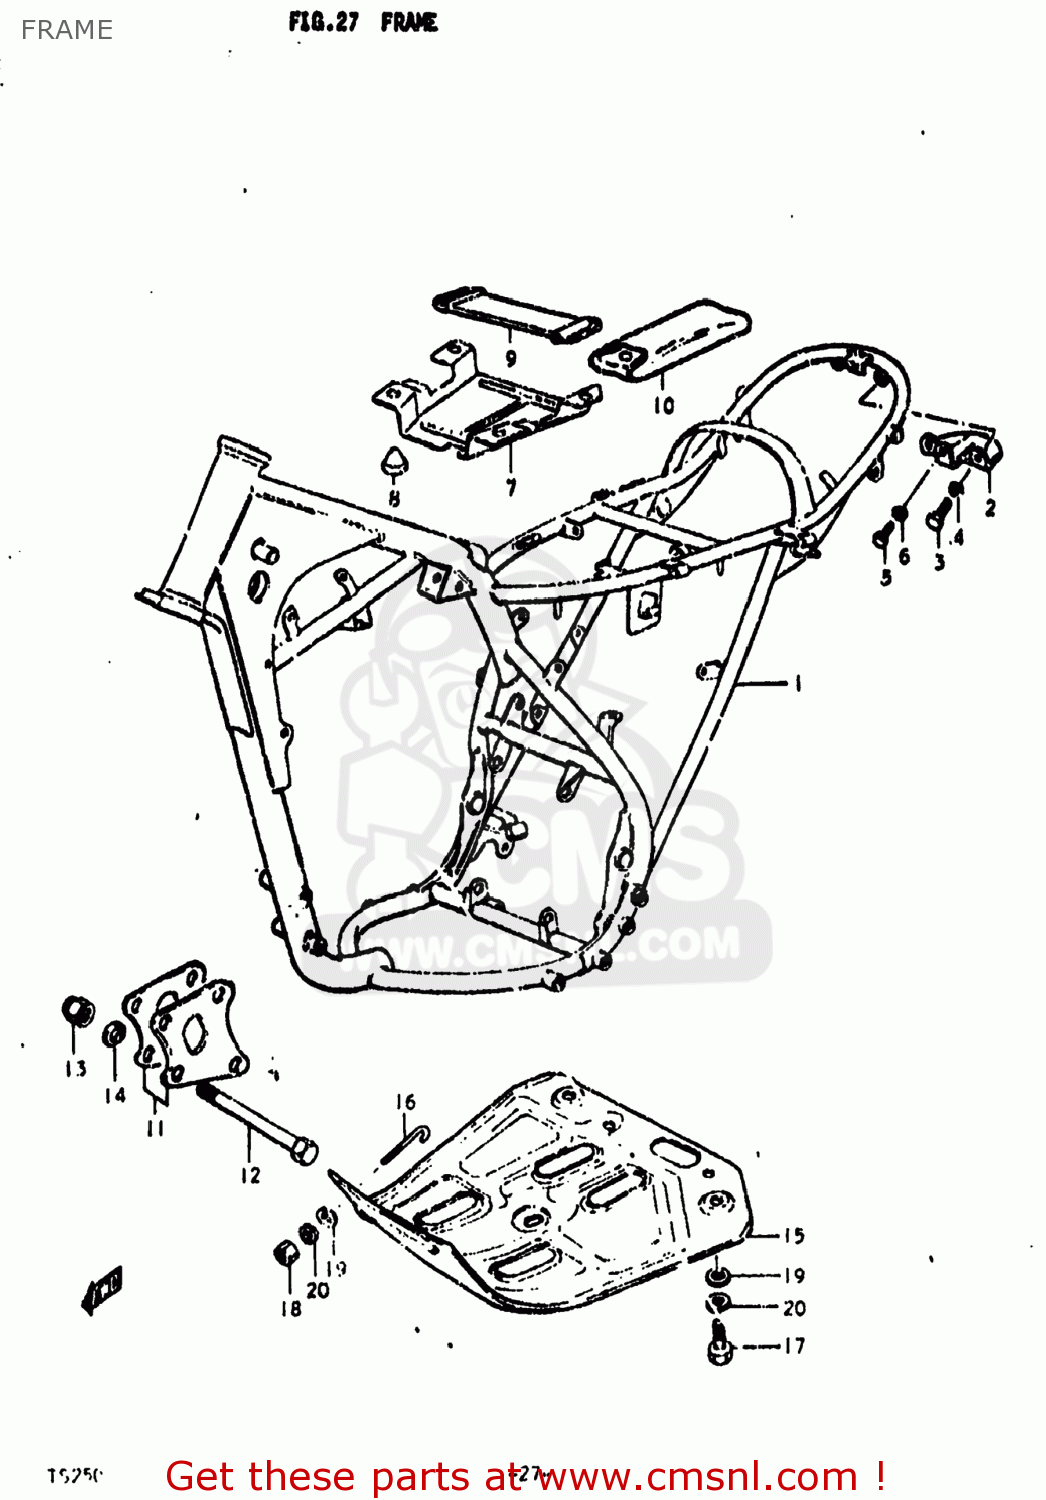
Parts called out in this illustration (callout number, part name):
1	FRAME
3	BOLT
4	LOCK WASHER
5	BOLT
6	LOCK WASHER
7	HOLDER,TOOL
8	CUSHION
9	BAND
10	TOOL ASSY
11	PLATE,ENGINE MOUNTING
12	HEXAGON BOLT 8X80
13	NUT
14	WASHER
15	GROMMET
16	BRACKET,ENGINE PROTECT
17	BOLT
18	NUT
19	WASHER
20	LOCK WASHER
